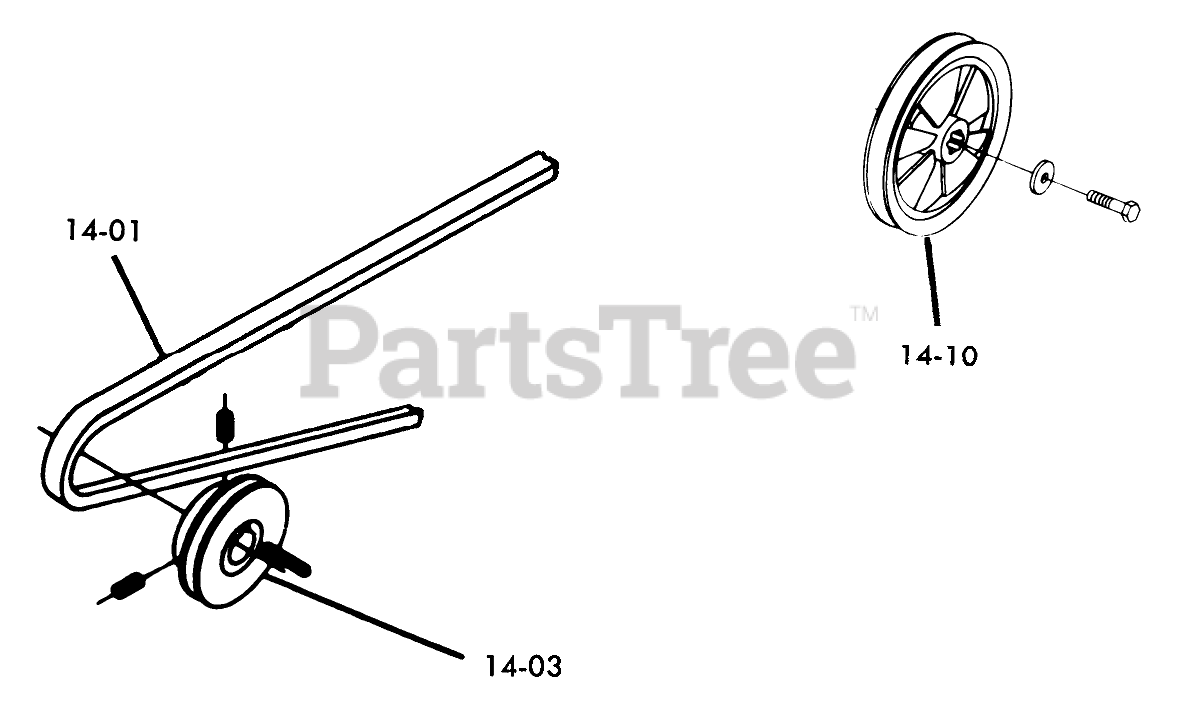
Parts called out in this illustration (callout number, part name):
14-01	V BELT
14-03	PULLEY
14-03	Key
14-03	Set Screw
14-10	PULLEY
14-10	WASHER
14-10	Bolt
